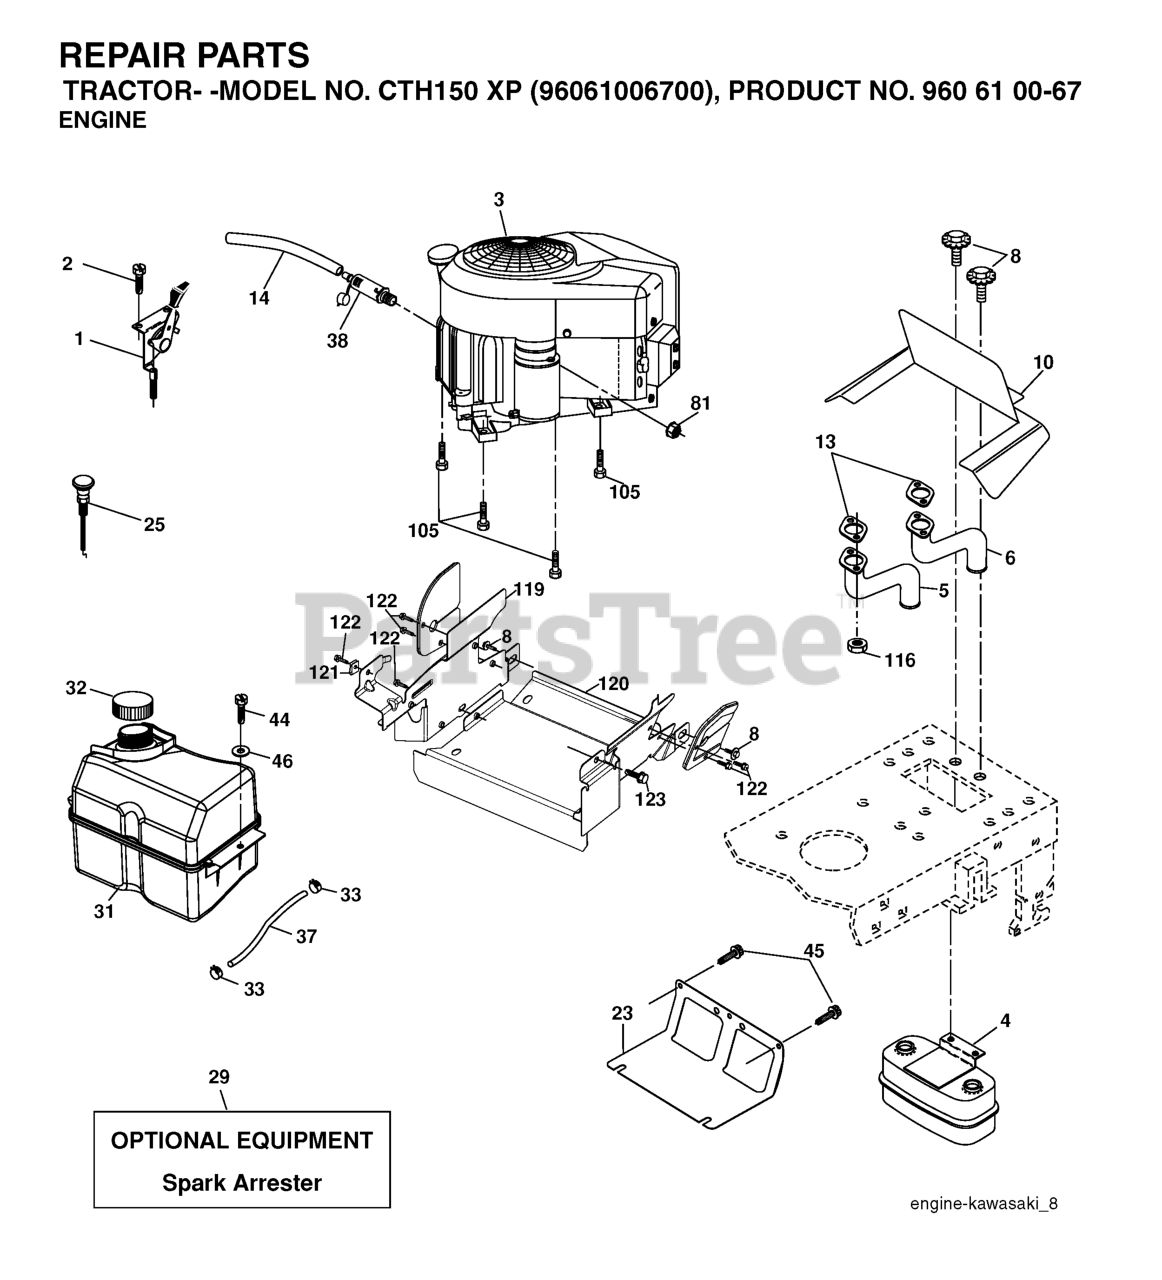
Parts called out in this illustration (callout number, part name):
1	CONTROL, THROTTLE
2	SCREW
4	MUFFLER.TWIN.CYL.LOW.TONE
5	EXHAUST TUBE RH KAWI
6	EXHAUST TUBE LH KAWI
8	BOLT.5/16-18UNCX3/4 W/SEMS.BLK
10	RP SHIELD HEAT MUFFLER
14	TUBE, DRAIN OIL ASM.
23	SHIELD.BROWNING.DBR.GUARD
29	KIT.SPARK ARRESTOR 794945 B&S
31	TANK FUEL
32	FUEL CAP
33	HOSE CLAMP
37	LINE.FUEL.20
44	SCREW HEXWSHR 1/4-20X3/4
45	SCREW, 3/8-16X3/4
81	NUT
105	SCREW 3/8-16X1
116	NUT.HEX.FLANGE.TOPLOCK
122	SCREW.1/4-20X5/8
123	SCREW, 5/16-18 X 1/2
